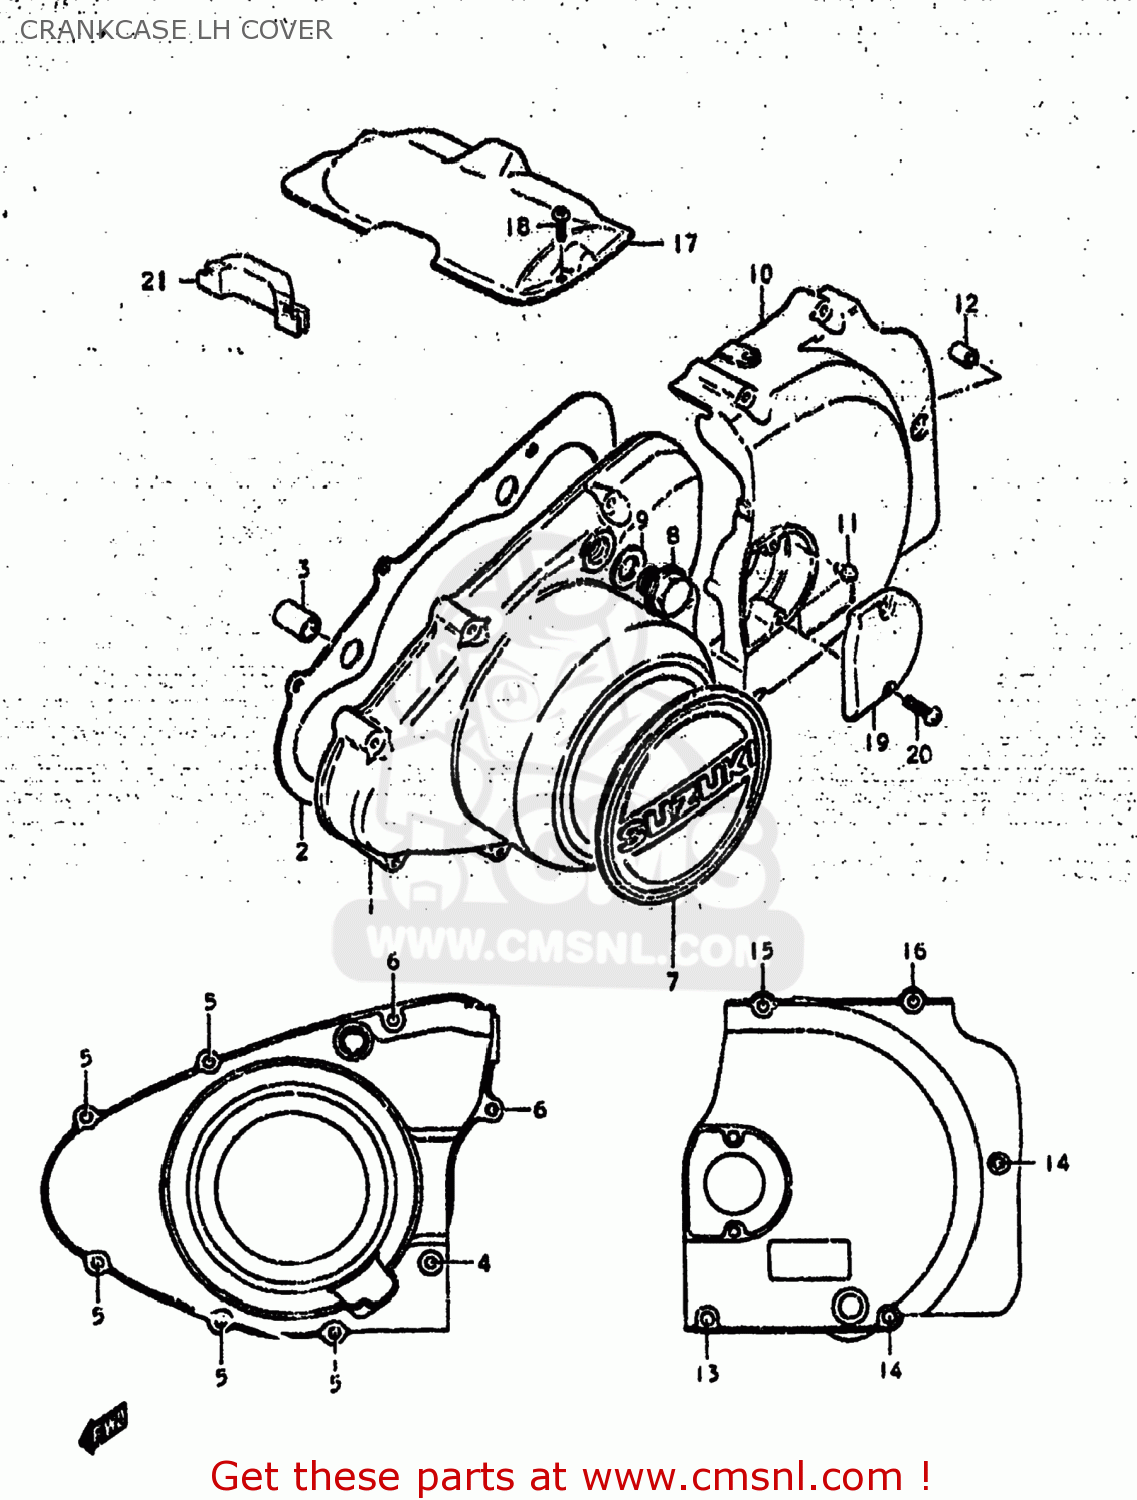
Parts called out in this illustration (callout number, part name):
1	COVER
2	GASKET,MAGNETO COVER (MCA)
3	PIN
4	SCREW
5	SCREW (6X35)
6	SCREW 6X30
7	EMBLEM,MAGNETO COVER
8	PLUG (14X12)
9	GASKET(14X19.2X2) (NAS)
10	COVER,ENGINE SPROCKET
11	NIPPLE
12	PIN
13	SCREW 6X65
14	SCREW 6X60
15	SCREW
16	SCREW 6X30
17	COVER,STARTER MOTOR
18	SCREW
19	CAP,CLUTCH RELEASE ADJUST
20	SCREW
21	GROMMET,STARTING MOTOR
